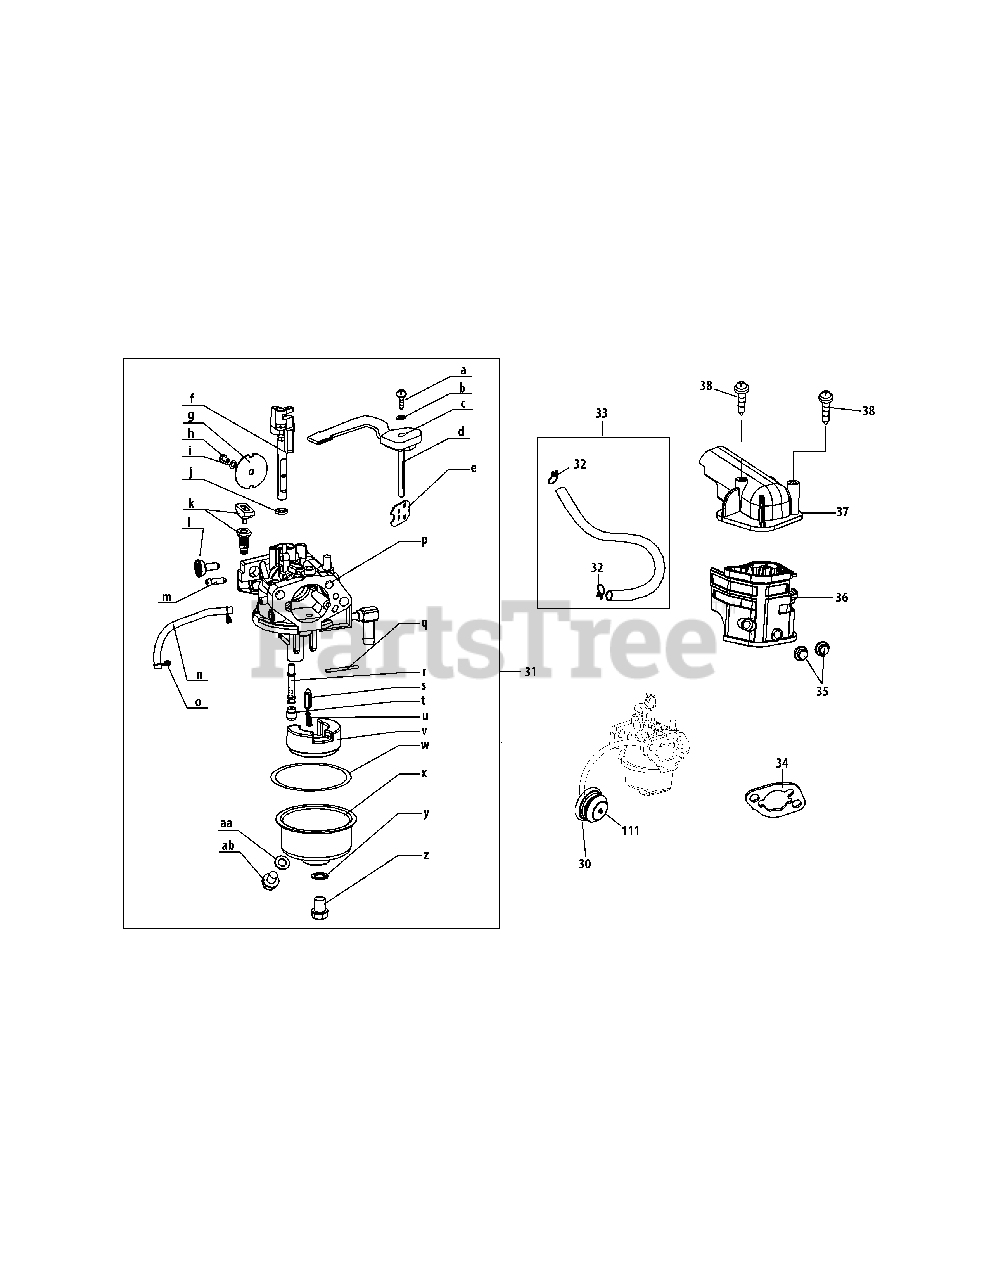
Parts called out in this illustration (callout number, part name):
30	Primer Assembly
31	Carburetor Assembly
32	Fuel Hose Clamp
33	Fuel Line Kit
34	Carburetor Gasket Plate
36	Intake Heater Box Base
37	Intake Heater Box
38	Self-Tapping Bolt M4.2×16
111	Primer Bulb
